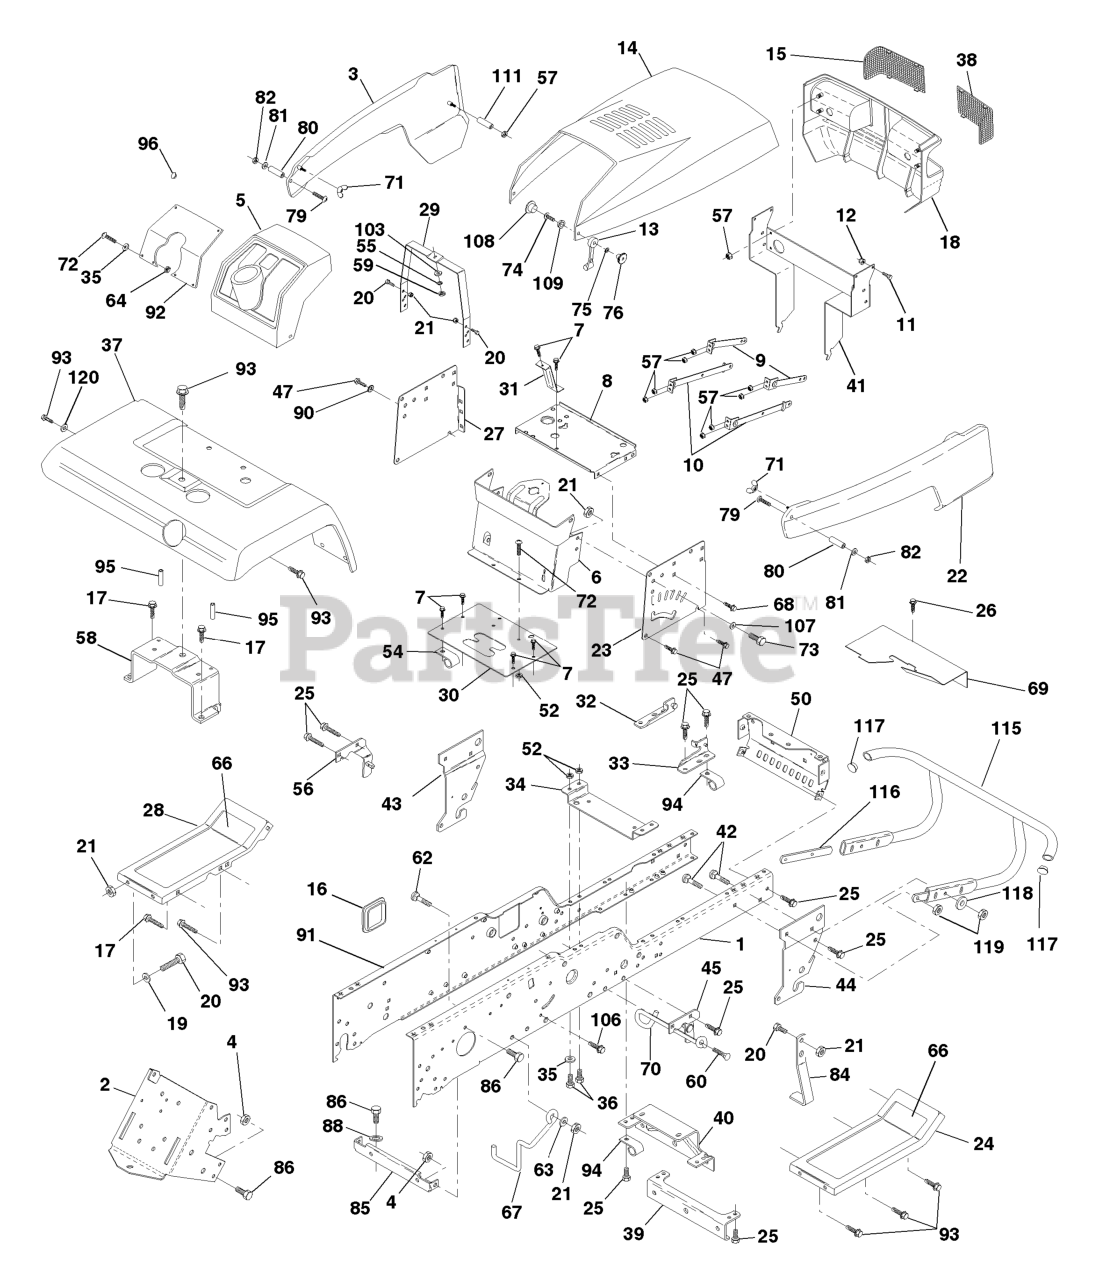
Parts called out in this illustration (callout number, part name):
1	RAIL, FRAME RH
2	DRAWBAR-GT
3	SIDE PANEL ASSY LH
4	Nut, Lock Hex 7/16 Unc
6	LOWER DASH ASSY
7	SCREW
8	BATTERY SUPPORT
9	STRAP ASSY LT
10	STRAP ASSY LT
11	BOLT T
12	LOCKNUT.NYLOC.1/4-20
13	LATCH.HOOD.
14	HOOD.HUSQVARNA.ORANGE
15	LENS LH
16	COVER ACCESS
17	SCREW
18	GRILL COMPLETE
19	WASHER
20	BOLT
21	NUT
22	SIDE PANEL ASSY RH
23	PANEL, DASH RH
24	PAD,SPACER
25	SCREW
26	SCREW.THDROL.5/16-18X3/4.TTY
27	PANEL, DASH LH
28	ROLL PIN NLA
29	SUPPORT ASS'Y
30	FRAME SADDLE
31	STEERING SUPPORT BRACE
32	FRAME PIVOT BRKT ASSY LH
33	FRAME PIVOT BRKT ASSY RH
34	ENGINE SUPPORT BRKT
35	WASHER
36	BOLT.FIN.HEX.5/16-18X3/4
37	FENDER
38	LENS RH
39	FRONT AXLE BRACKET
40	AXLE SUPPORT BRKT
41	GRILL SUPPORT ASSY
42	BOLT D
43	FRONT SUSPENSION BRKT LH
44	FRONT SUSPENSION BRKT RH
45	CHASSIS BRKT
47	SCREW LT
50	CHASSIS BRKT
52	NUT.71038.31-18.HEX.NYLOCK
54	CLIP,INSULATOR
55	WASHER PM
56	SUSPENSION BRKT LH
57	NUT
58	FENDER BRKT
59	NUT
60	SCREW
62	BOLT D
63	WASHER
64	NUT
66	PAD FOOTREST T
67	BELT GUIDE
68	Screw, Thdrol 5/16-18 x 1/2
69	HEAT SHIELD
70	BELT GUIDE
71	WING NUT
72	Screw, Mach Trhd 5/16-18 x 3/4
73	BOLT
74	SCREW
75	LOCKWASHER #10
76	WELDNUT
79	RP SCREW
82	NUT **
84	MOWER STOP
85	BRKT SUPPORT GT
86	BOLT
88	LOCKWASHER
90	LOCKWASHER
91	RAIL, FRAME LH
92	DASH PLATE
93	SCREW LT
95	NUT-PUSH YT
96	PLUG-DASH T
103	LOCKWASHER
106	SCREW
107	WASHER
108	SNAP CAP LT
115	BUMPER ASSY
116	BRACKET BUMPER
117	PLUG PLASTIC
118	WASHER
120	WASHER
